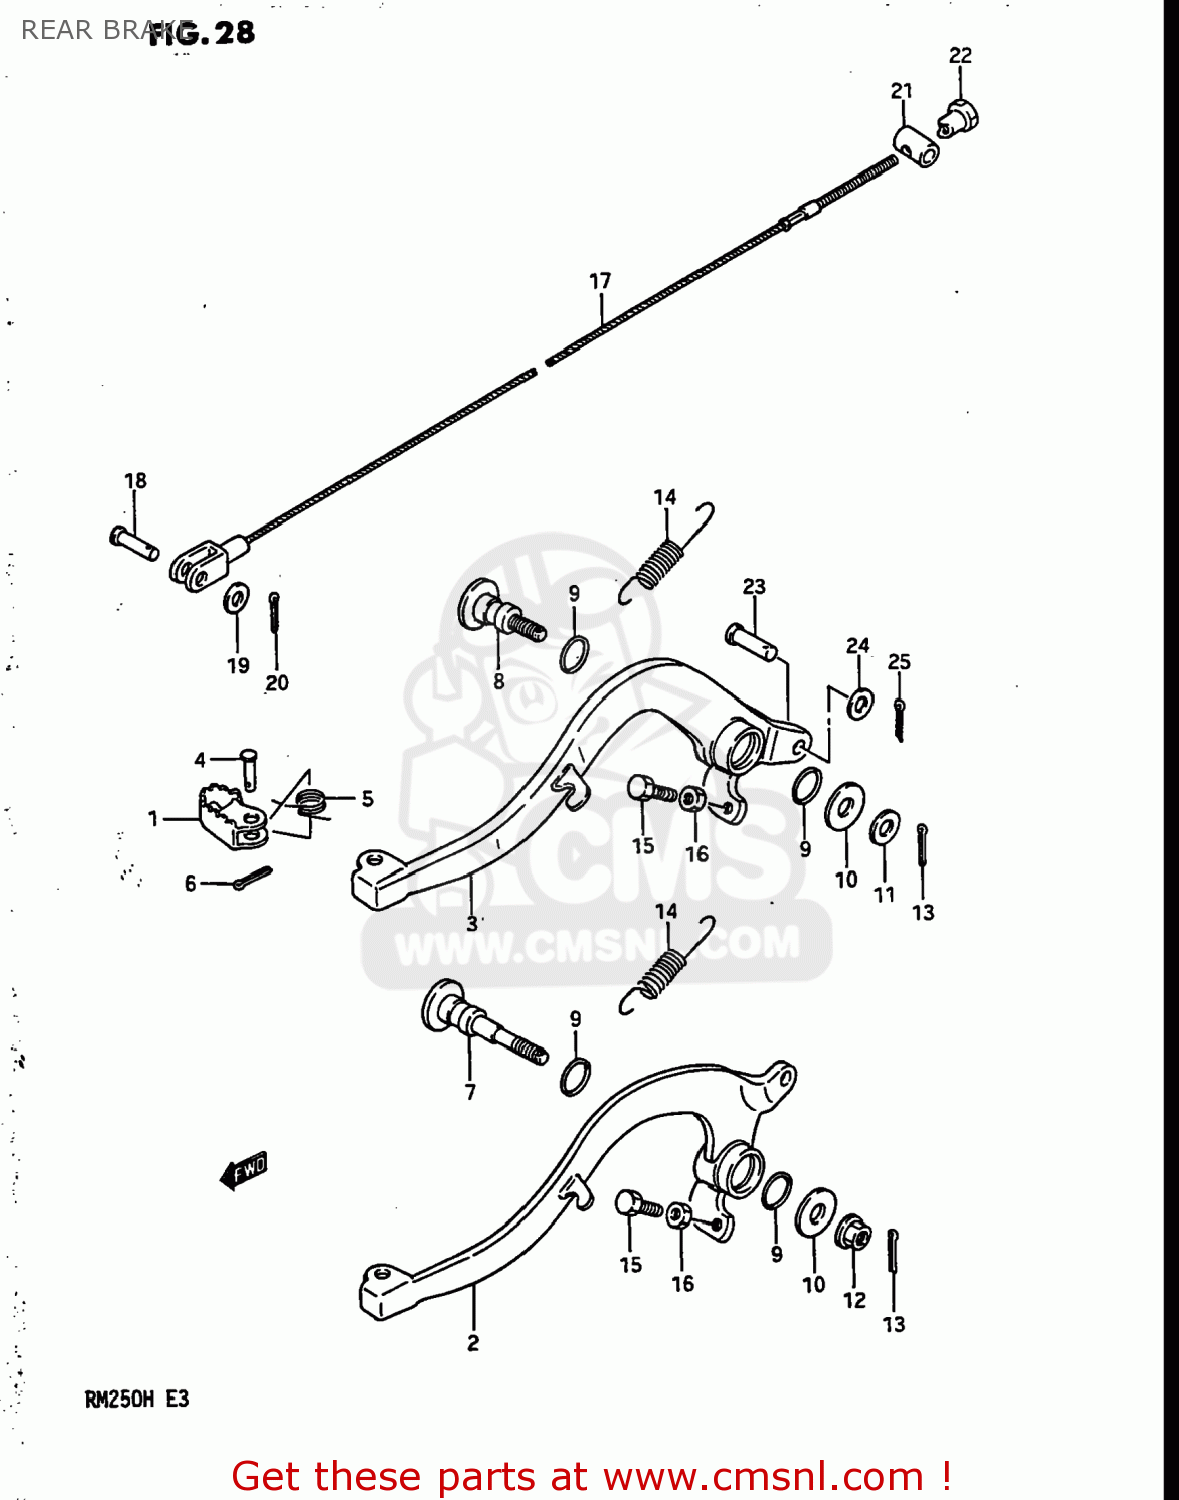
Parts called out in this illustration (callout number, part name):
1	PEDAL,BRAKE
2	ARM COMP,BRAKE PEDAL
3	ARM,BRAKE PEDAL
4	PIN
5	SPRING
6	PIN
7	SHAFT,BRAKE PEDAL
8	SHAFT,BRAKE PEDAL
9	O-RING,BOSS
10	WASHER
11	WASHER
12	NUT
13	PIN 20X20
14	SPRING BRAKE PEDAL
15	BOLT
16	NUT
17	CABLE,RR BRAKE
18	PIN(L:17.5)
19	WASHER
20	PIN 20X20
21	PIN
22	NUT (6MM)
23	PIN(8X20)
24	WASHER(8.5X13X1.6)
25	PIN
